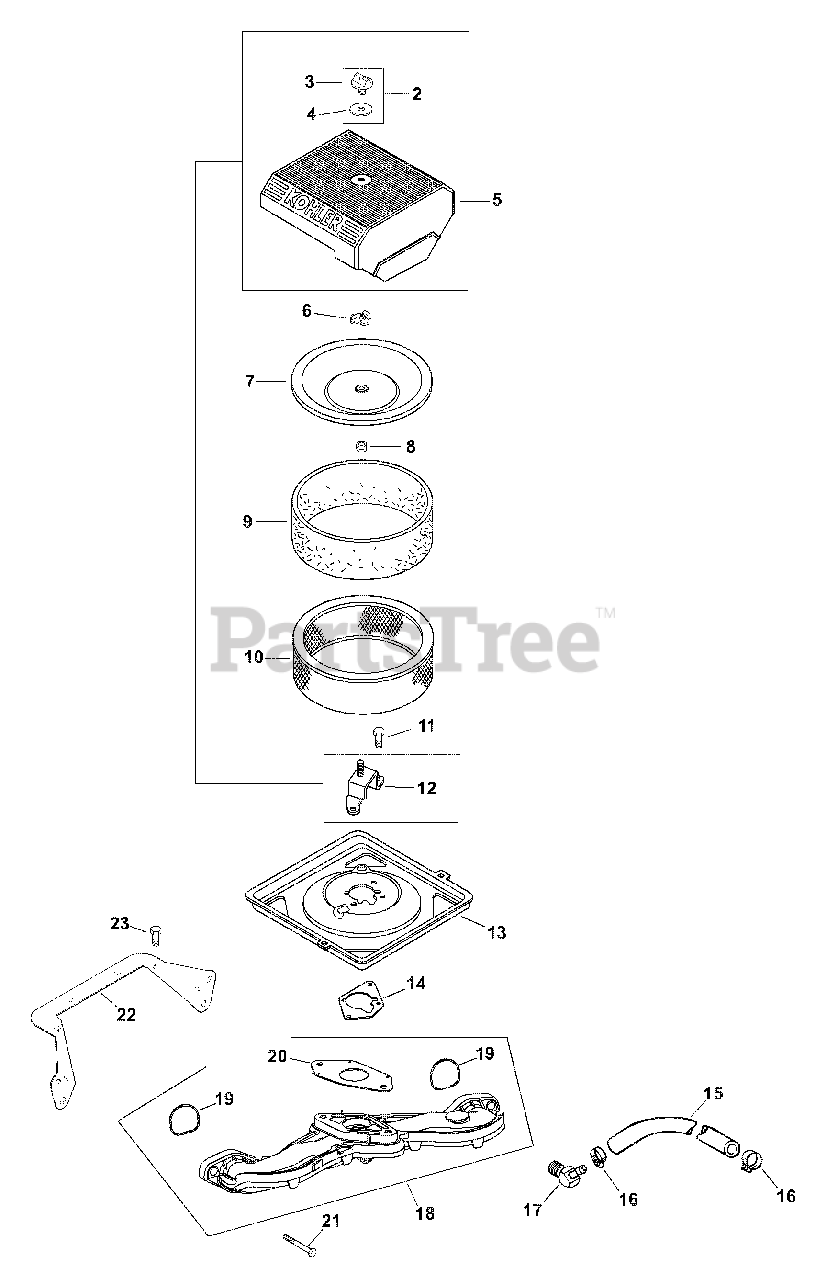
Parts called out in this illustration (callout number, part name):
1	Kit, air cleaner cover
2	Kit, knob with seal
3	Knob, cover
4	Seal, air cleaner cover knob
5	Cover, air cleaner
7	Cover, inner air cleaner
8	Seal, inner air cleaner
9	Precleaner, element
10	Element, air cleaner
11	Screw, hex. flange M6x1.0x16
12	Bracket, air cleaner base
13	Base, air cleaner
14	Gasket, air cleaner base
15	Line, fuel
16	Clamp, hose
17	Connector, pulse fitting
18	Manifold, intake
19	O-Ring, intake port
20	Gasket, carburetor
21	Screw, hex. flange M6x1.0x40
22	Bracket, air cleaner
23	Screw, hex. flange M5x0.8x10
